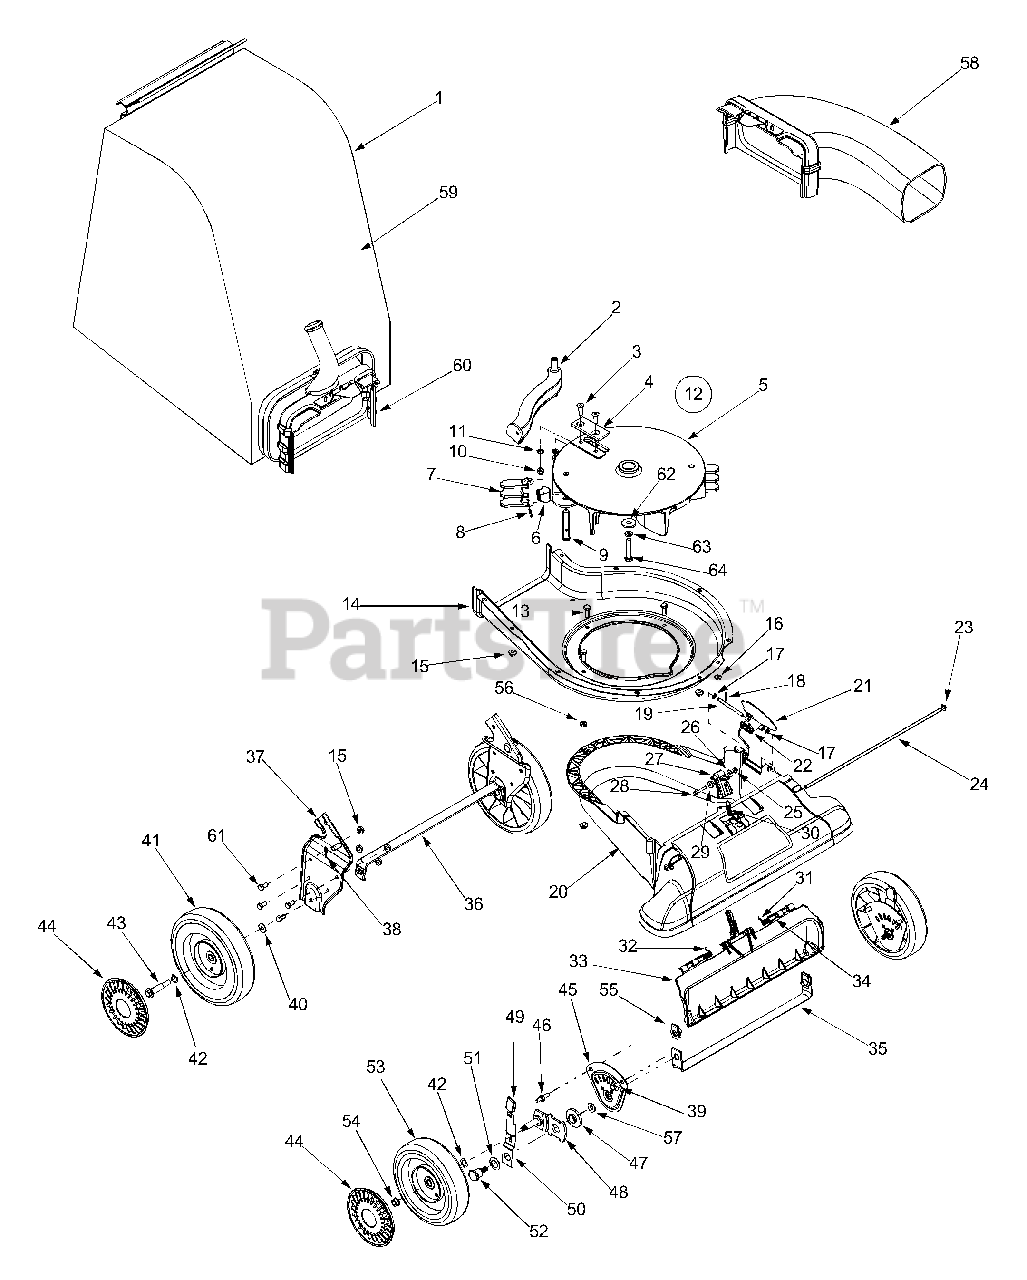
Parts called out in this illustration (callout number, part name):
1	Bag Assembly
3	Hex Screw 5/16-24 x 1.0
4	Chipper Blade
5	Impeller
6	Pin Clip
7	Flail
8	Spiral Pin
9	Clevis Pin
10	Lock Nut, 5/16-24
11	Lock Washer, 5/16
12	Impeller Assembly
13	Hex Cap Screw 5/16-18 x .875
15	Flange Lock Nut 5/16-18
16	Hex Flange Nut 1/4-20
17	Flat Washer .281 ID x .50 OD
18	Cotter Pin
19	Pivot Rod
20	Nozzle
21	Base Adapter Door
22	Torsion Spring
23	Cap Speed Nut 1/4
24	Pivot Rod
25	Hex Lock Nut #10-24
26	Flat Washer .194 ID x .62 OD
27	Nozzle Door Lever
28	Hex Screw #10-24 x 1.25
29	Shoulder Spacer
30	Extension Spring
31	Torsion Spring LH
32	Torsion Spring RH
33	Nozzle Door
34	Rod .25 x 1.25 Lg
38	Cotter Pin
39	Hex Cap Screw 5/16-18 x. 625
40	Bell Washer.401 ID x.870 OD
41	Wheel 9 x 2
42	Wave Washer .531 ID x .781 OD
43	Shoulder Screw 3/8-16
44	Hubcap
47	Height Adjustment Bearing
48	Pivot Arm Assembly
49	Height Adjustment Knob
50	Spring Lever
51	Bell Washer .760 ID x .25 OD
52	Shoulder Screw .750 ID x .625 OD
53	Wheel 8 x 2
54	Flange Lock Nut 3/8-16
55	Lock Nut 3/8-16
56	Hex Lock Nut 5/16-18
57	Thrust Washer .375 ID x .70 OD
58	Blower Chute
59	Bag
60	Chute Assembly
61	Hex Index Screw, 5/16-18 x .75
62	Flat Washer.375 ID x 1.25 OD
63	Lock Washer 3/8
64	Hex Cap Screw 3/8-24 x 2.0
